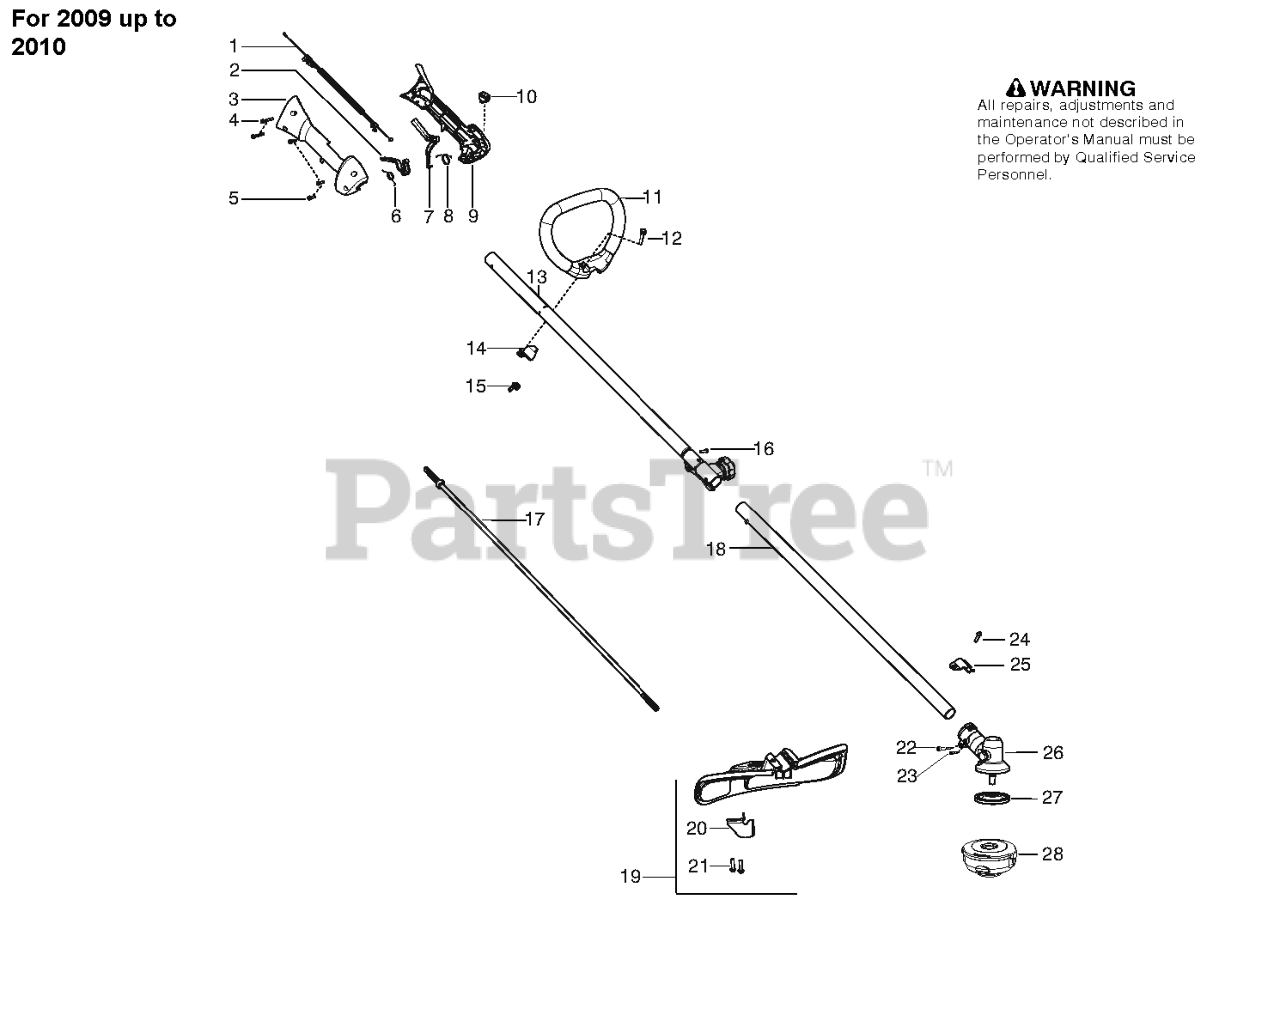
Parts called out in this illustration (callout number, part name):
1	ASSY-CABLE WIRE HARNESS
2	TRIGGER THROTTLE
3	HOUSING-THROTTLE RH
5	SCREW M4 X 1.75 PT 16MM
6	SPRING TRIGGER
7	THROTTLE LOCKOUT
8	SPRING LOCKOUT
9	HSG THROTTLE LH
10	KIT SWITCH
12	BOLT, TYPE 2
13	KIT DRIVESHAFT UPPER SHAFT
14	CLAMP ASSIST HANDLE
15	WINGNUT, TYPE 2
18	KIT LOWER SHAFT
19	KIT COBI SHIELD
20	Limiter - Line
22	SCREW - CARB. ADAPTOR
24	SCREW 1/4-20 X 7/8 (TAP
25	BRACKET SHIELD STRAIGHT SHAFT
26	ASSY GEARBOX
27	DRIVE DISC
28	T25 TRIM HEAD 10MM LH
